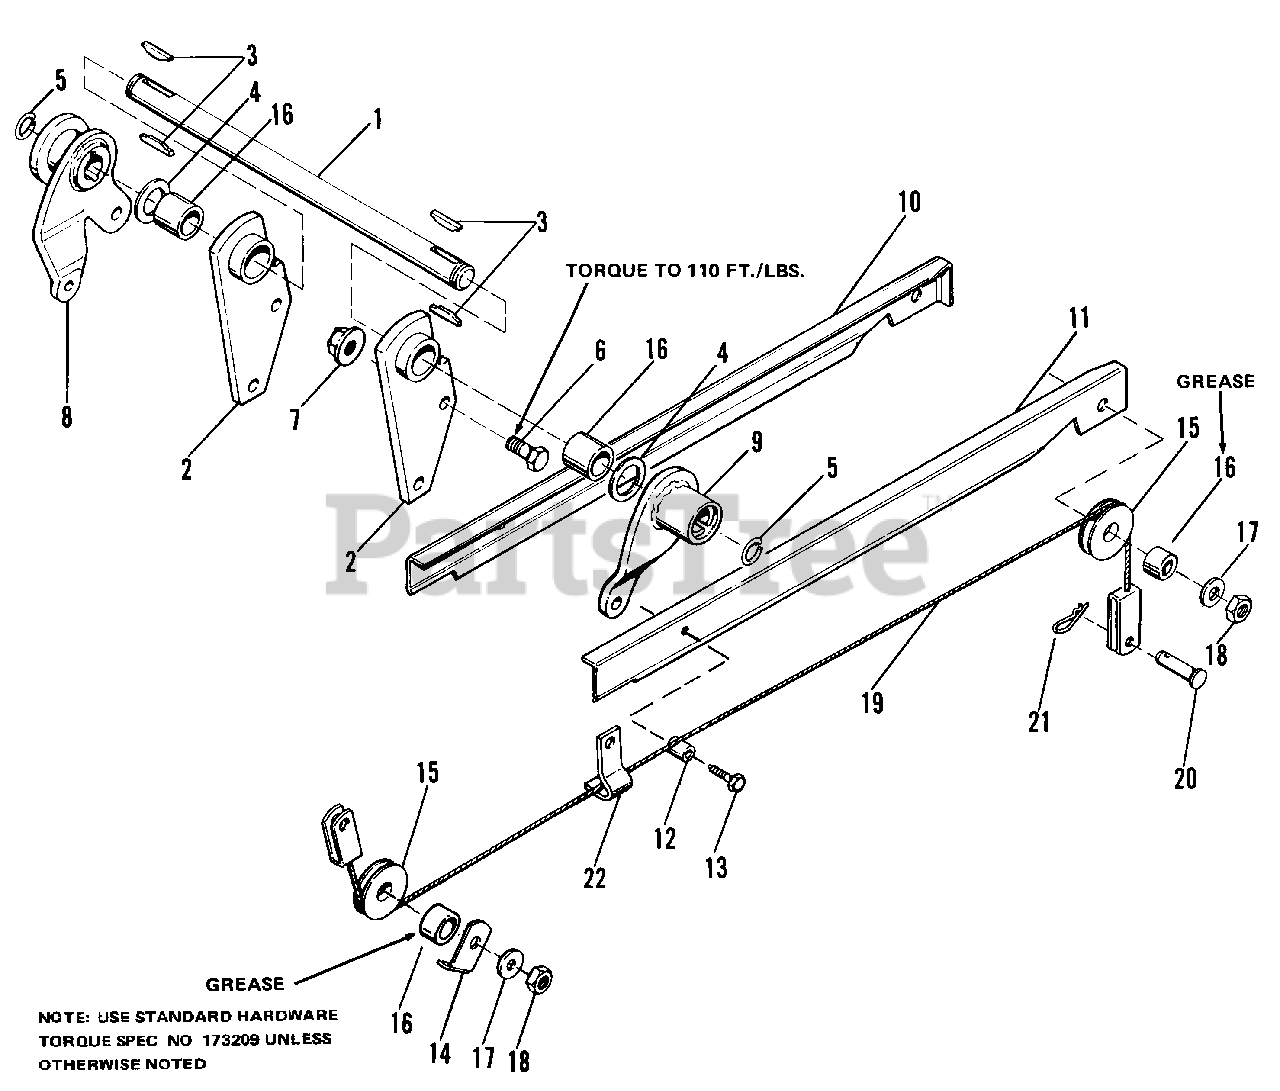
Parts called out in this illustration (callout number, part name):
1	SHAFT, Rocker
2	SUPPORT ASSY
5	RING, Retaining
6	CAPSCREW, Hex, 1/2-13 x 1-1/2
7	NUT, Lock, Flange, 1/2-13
8	ARM ASSY, Lift, L.H.
9	ARM ASSY, Lift, R.H.
10	GUARD, Wire, L.H.
11	GUARD, Wire, R.H.
13	SCREW, Thd. Forming, 1/4 x 1-1/4
14	GUIDE, Wire
15	PULLEY, Cable
17	WASHER, 7/16
18	NUT, Hex, Lock, 1/2-13
21	CLIP, Spring
22	GUIDE, Wire
